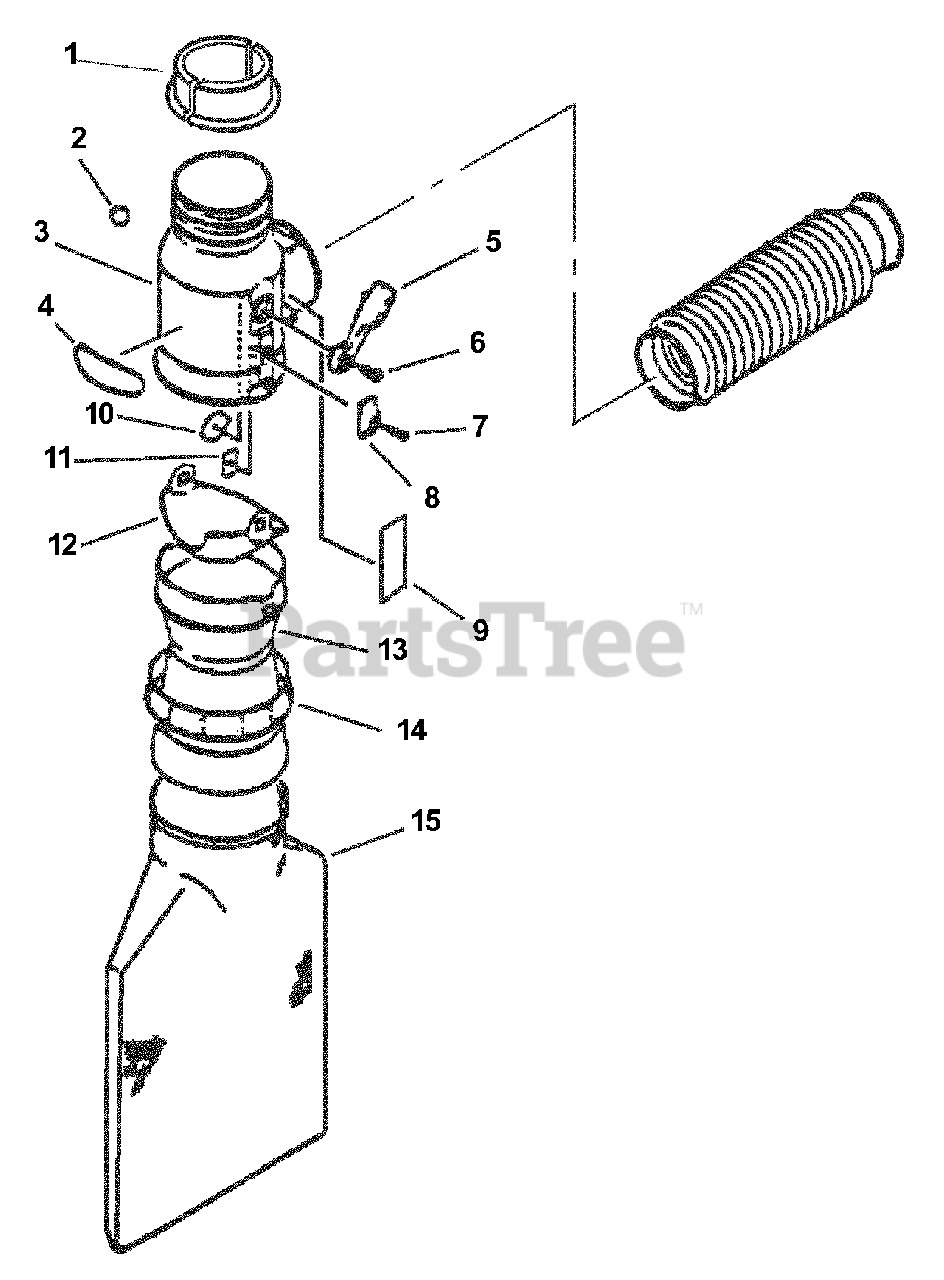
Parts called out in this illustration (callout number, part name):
1	COUPLER, SUCTION
2	RING, RETAINING - 8
3	TUBE, SUCTION
4	LABEL - ECHO
6	SCREW - 5X14
7	SCREW - 4X14
9	LABEL - FUNCTION
13	CONNECTOR
15	BAG, DEBRIS
